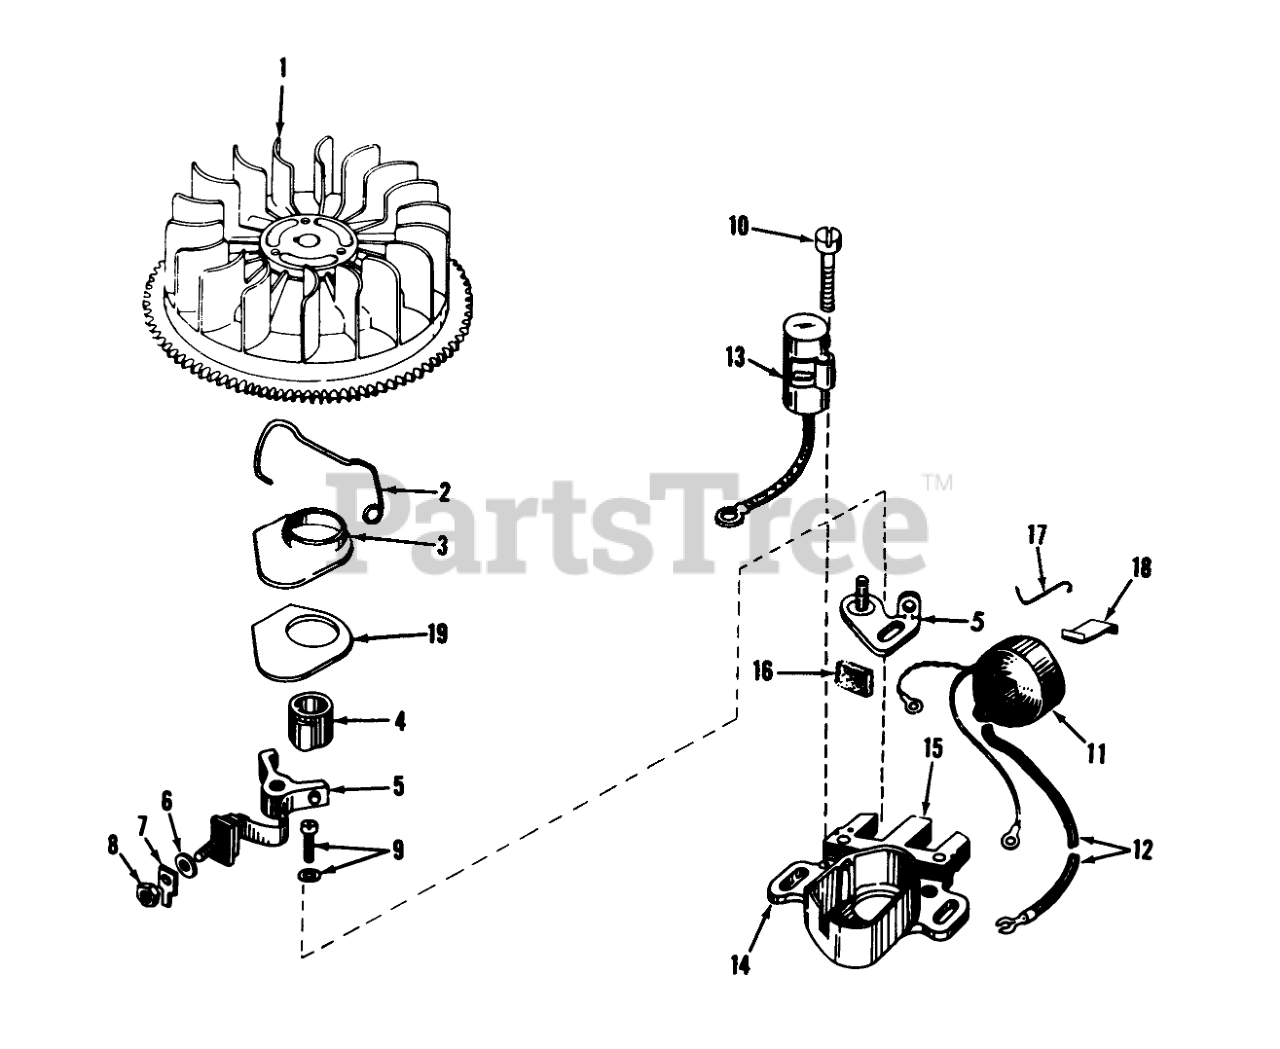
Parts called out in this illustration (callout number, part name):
1	Flywheel
2	Spring Breaker Box
3	Cover, Dust
4	Cam-Breaker
5	Breaker Assy.
6	Washer
7	Terminal, Ground
8	DECAL
9	Breaker Screw
10	Condenser Screw
11	Coil Assy., (Incl. #12)
12	Wire, Lead
13	Condenser
14	Core & Plate
15	Stator Assembly, (Incl. #2, 3, 5 thru 14 & 16 thru 19)
16	Felt,Cam Wiper
17	Clip, Coil
18	Spring Coil Wedge
19	Gasket, Dust Cover
